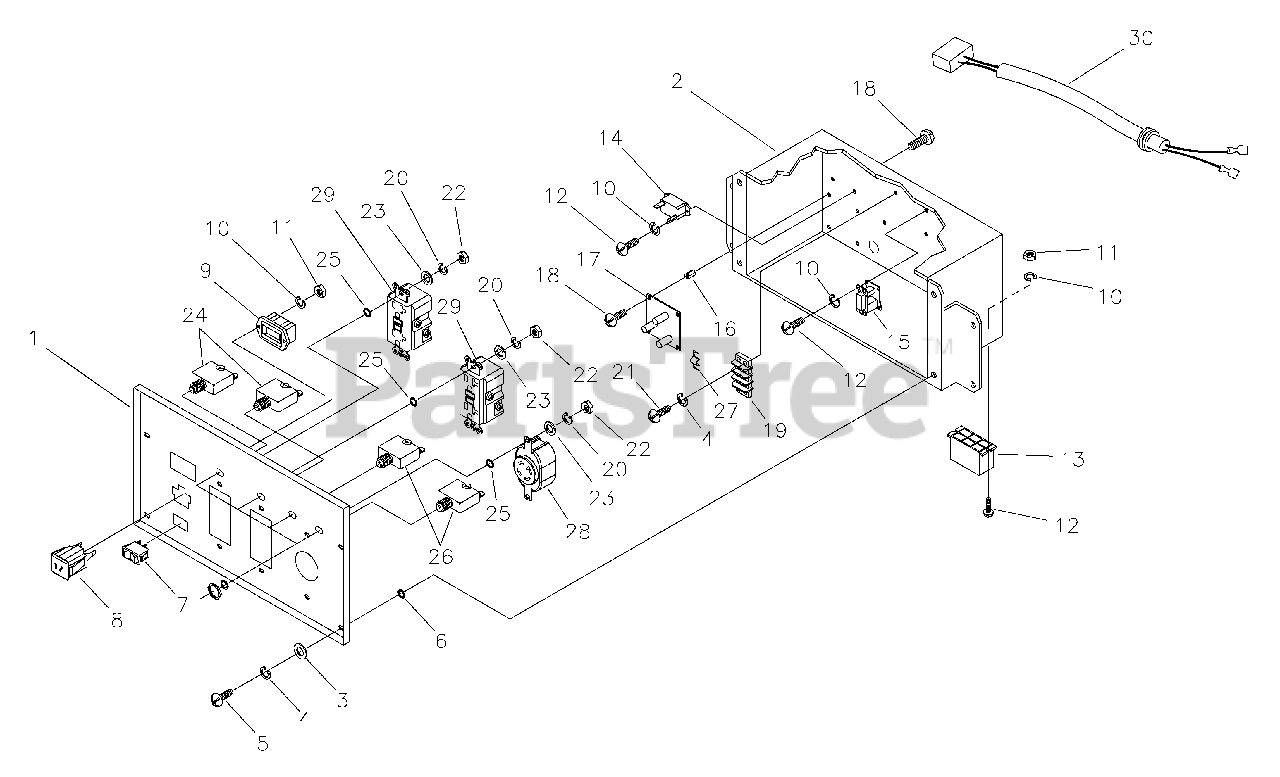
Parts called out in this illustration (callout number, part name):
1	PANEL, Control
2	BOX, Control Panel
3	WASHER, Flat, #10 - M5
4	WASHER, Lock, M5
5	PPHMS, M5 - 0.8 x 12
6	WASHER, M6 - 1/4, Int. Shakeproof
7	SWITCH, Rocker
8	OUTLET, 12VDC, Snap
9	METER, Hour
10	WASHER, Lock, M3
11	NUT, M3 - 0.5
12	PHMS, M3 - 0.5 x 10
13	HOUSING, Receptacle
14	BREAKER, Circuit, 12V, 10A
15	TRANSFORMER, Idle Cnt
16	STANDOFF, Hex
17	PCB, Idle Control
18	PHTS, #6-32 x 3/8
19	STRIP,Terminal
20	WASHER, Lock, M4
21	PPHMS, M5 - 0.8 x 20
22	NUT, M4 - 0.7
23	WASHER, Flat, M4
24	BREAKER, Circuit, 20A, with Hardware
25	WASHER, Shakeproof, Int. #8
26	BREAKER, Circuit, 25A, with Hardware
27	JUMPER,Terminal Block
28	OUTLET, 120/240V, 30A
29	OUTLET, 120V, 20A, Duplex. GFCI
30	HARNESS,Wire
